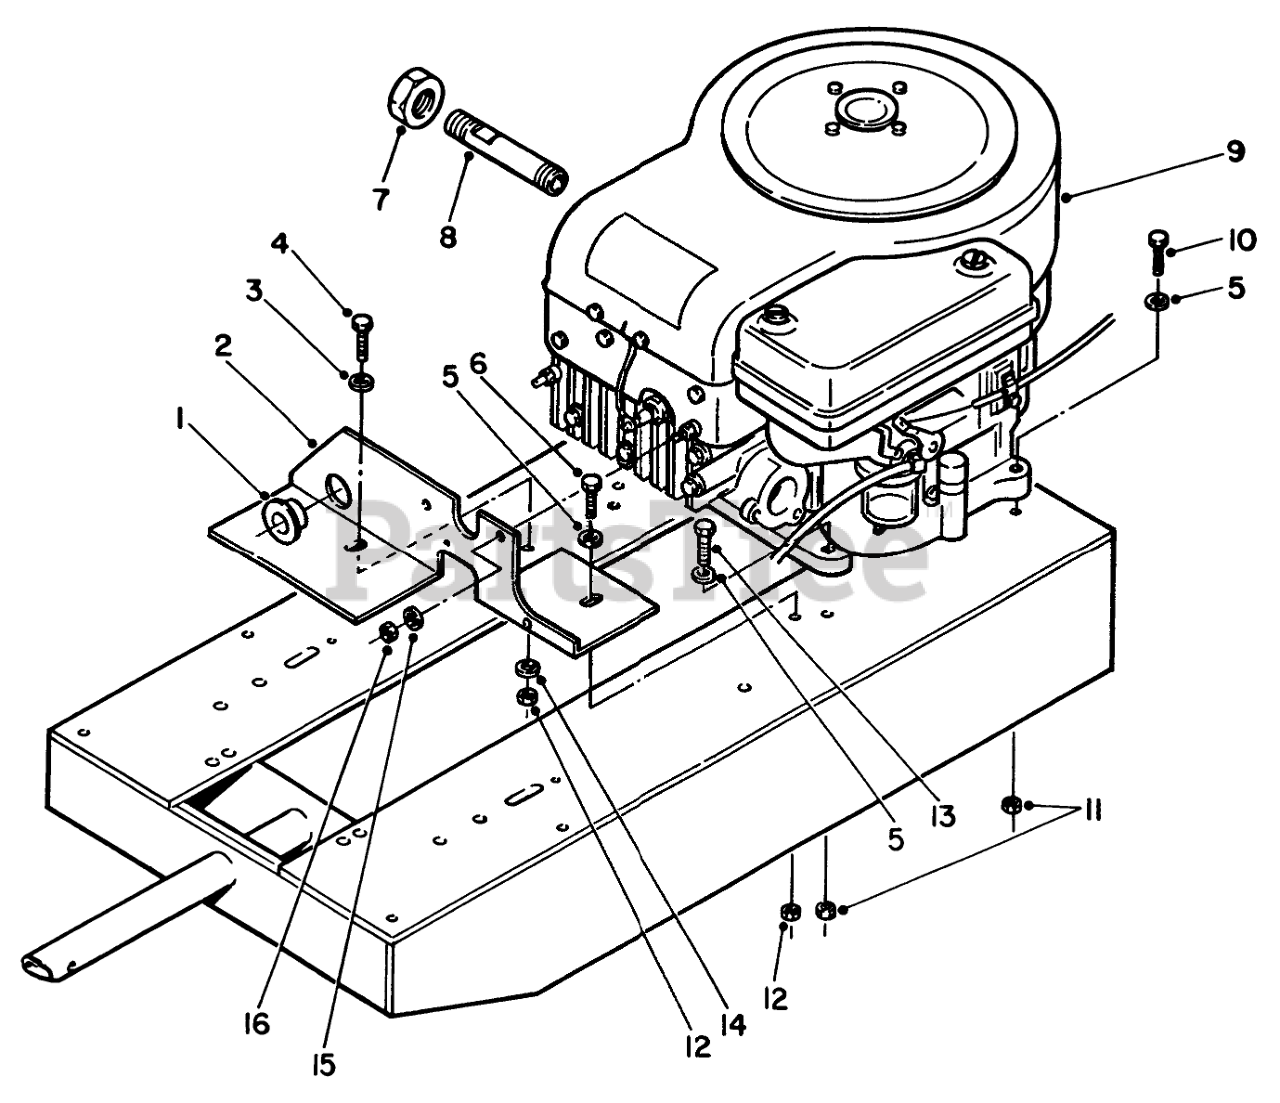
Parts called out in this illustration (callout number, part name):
1	BUSHING-NYLON 1.093
2	BRACKET-ENGINE HE R
3	WASHER-FLAT
4	SCREW-HH
5	WASHER-FLAT
6	SCREW-HH
7	Cap
8	PIPE-DRAIN B
9	Engine-Order from Briggs
10	SCREW-HH
11	NUT-LOCK, NI
12	NUT-LOCK, NI
13	SCREW-HH
14	WASHER
15	WASHER-LOCK
16	NUT-HEX
